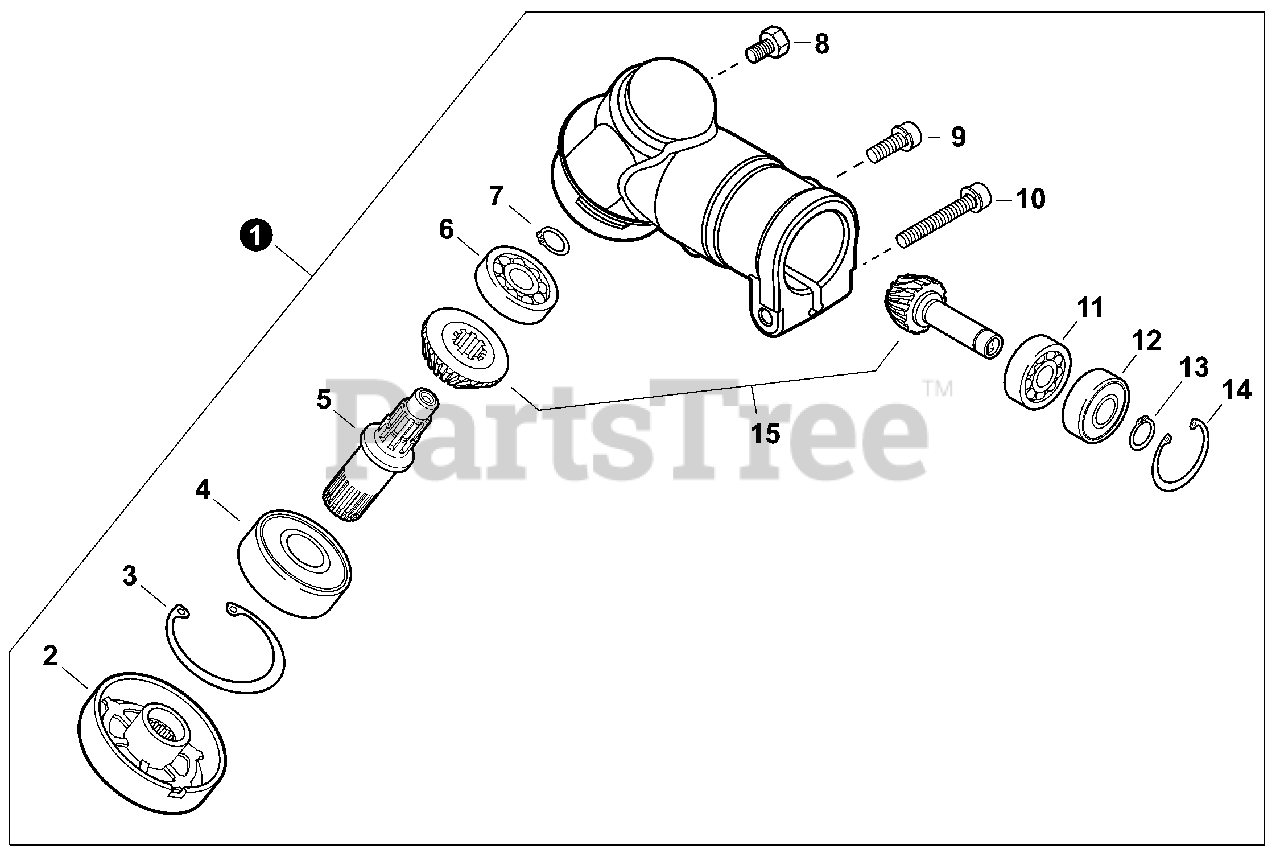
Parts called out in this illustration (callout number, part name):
1	GEAR CASE ASSY
2	PLATE, ADAPTOR - UPPER
3	RING, SNAP 26
4	BEARING, BALL 6000DDU
5	SHAFT, GEAR
6	BEARING, BALL 626
7	RING, SNAP Ø6
8	BOLT M8×8
9	SCREW 5×12
10	BOLT M5×35
11	BEARING, BALL 609
12	BEARING, BALL 609
13	RING, SNAP Ø9
14	RING, SNAP 24
15	GEAR SET
